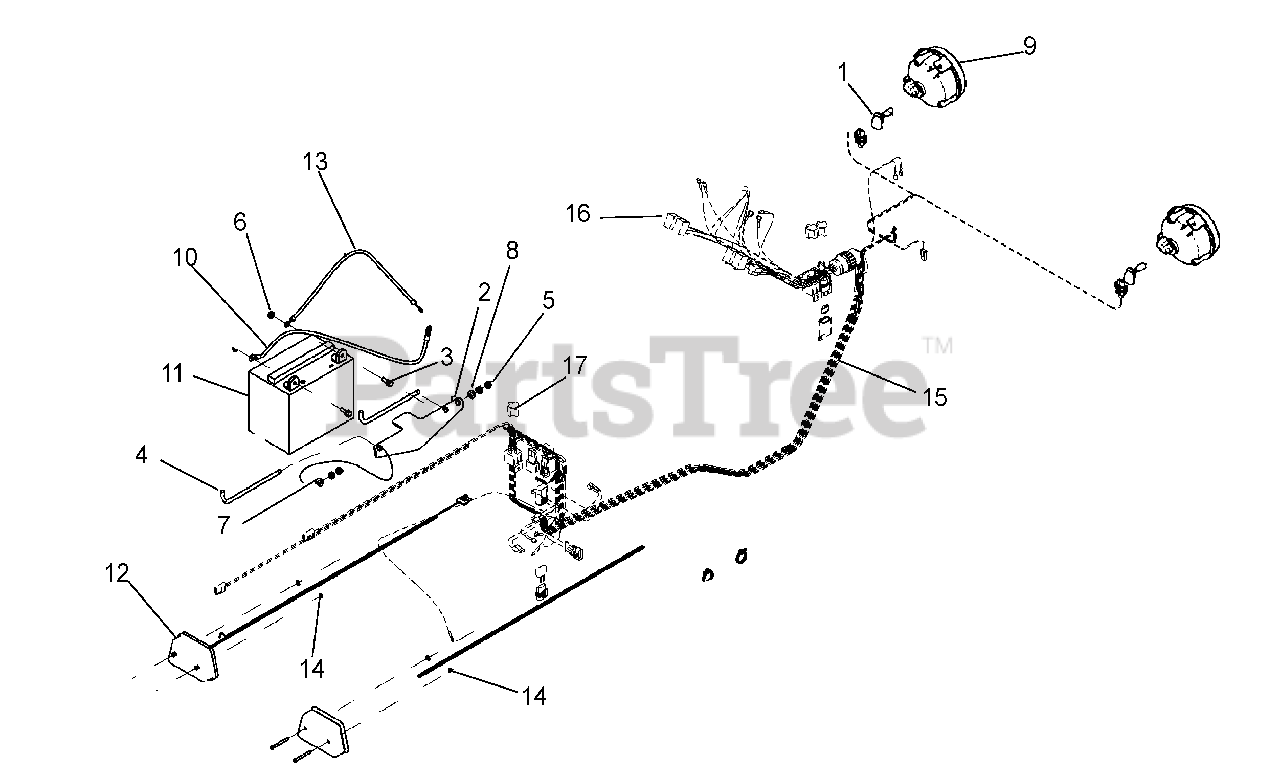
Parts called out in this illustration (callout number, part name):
1	HEADLIGHT BULB 37.5 WATT 894
2	HOLDOWN, BATTERY ST
3	SCREW, HEX FLANGE .25-20 X .625
4	SP HOOK 5/16-18 X 9 X 3 THREAD
5	NUT, HEX 5/16-18 YWZC
6	NUT, HEX FLANGE T-LOCK 1/4-20 YLW
7	WASHER, FLAT STEEL .312 X .734 X .065
8	WASHER, LOCK .31 X .078 REG YWZC
9	HEADLIGHT, ROUND
10	BATTERY CABLE POSITIVE 15 INCH
11	BATTERY (BUY LOCALLY BCI Group U1/U1R, Min. 300CA)
12	TAIL LIGHT, LED
13	20" 6GA NEGATIVE BLACK CABLE
14	PUSH RETAINERS 4 NON-THRD SHFT
15	WIRE HARNESS, MAIN
16	WIRE HARNESS, SUB DASH
17	RELAY, ISO MINI ELEC.
